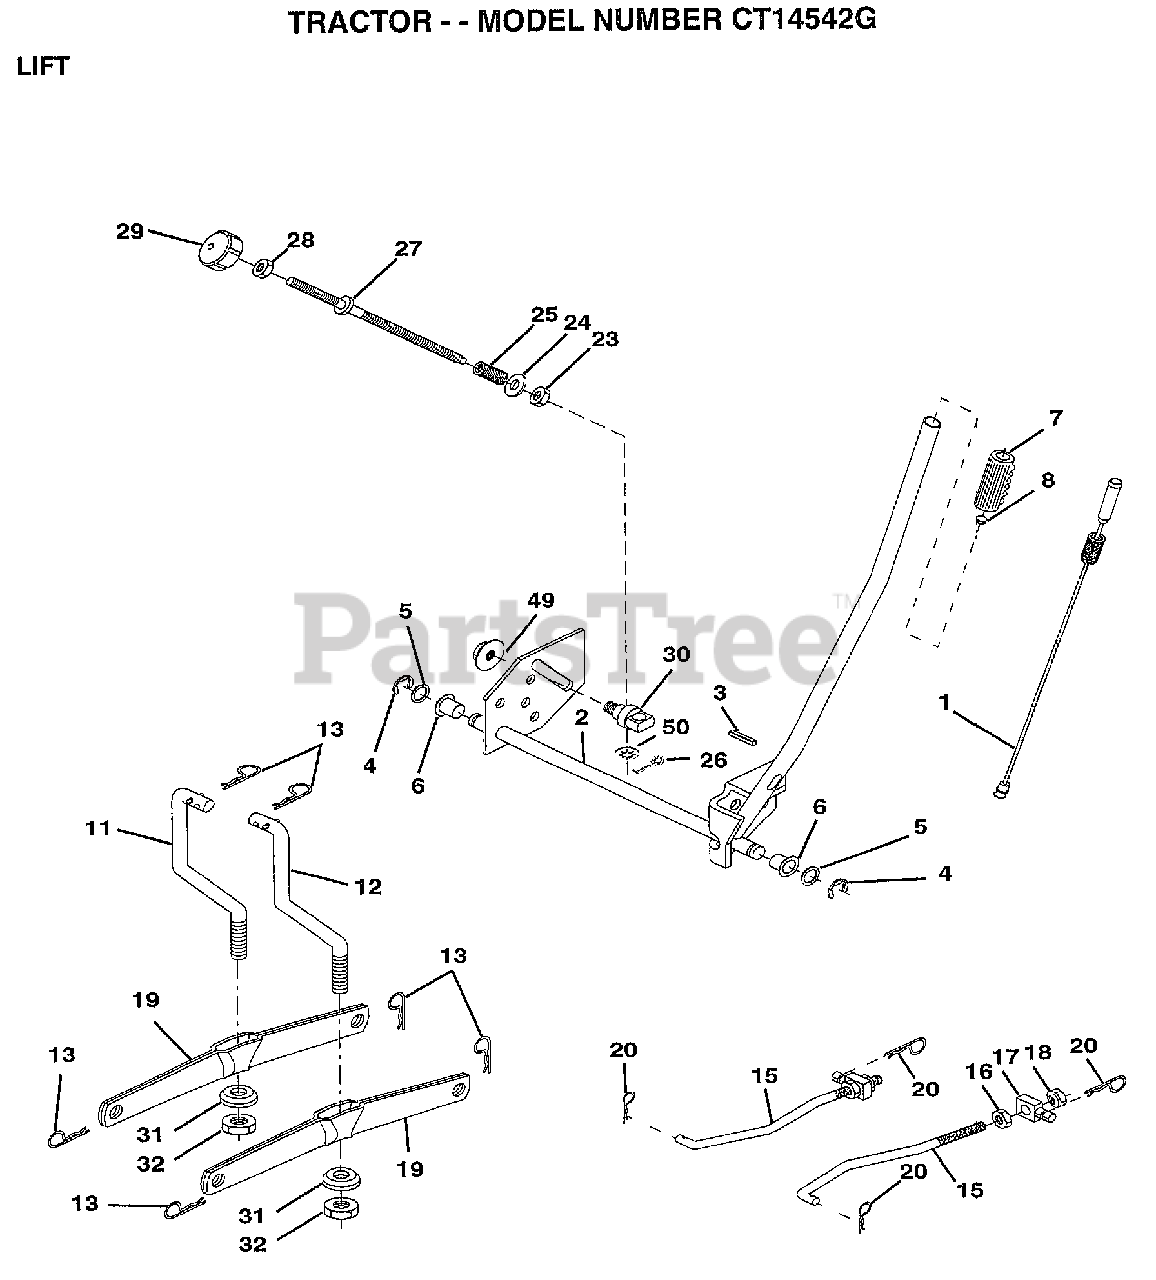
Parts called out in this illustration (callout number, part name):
1	WIRE ASM W.SPRING
2	"SHAFT ASM LIFT,RH"
3	PIN-GROOVE LT
5	WASHER
6	NYLON BEARING
7	GRIP
15	LINK.FRONT
16	NUT
17	TRUNION
18	NUT LTV
19	ARM SUSP REAR
20	RETAINER SPRING
23	NUT T
24	WASHER
25	SPRING T
28	NUT
29	KNOB INF 3/8-16
30	TRUNNION
31	BEARING PVT LH
32	NUT.CROWNLOCK.3/8
49	NUT.HXFLG.LOCK.
50	NUT PUSH M
